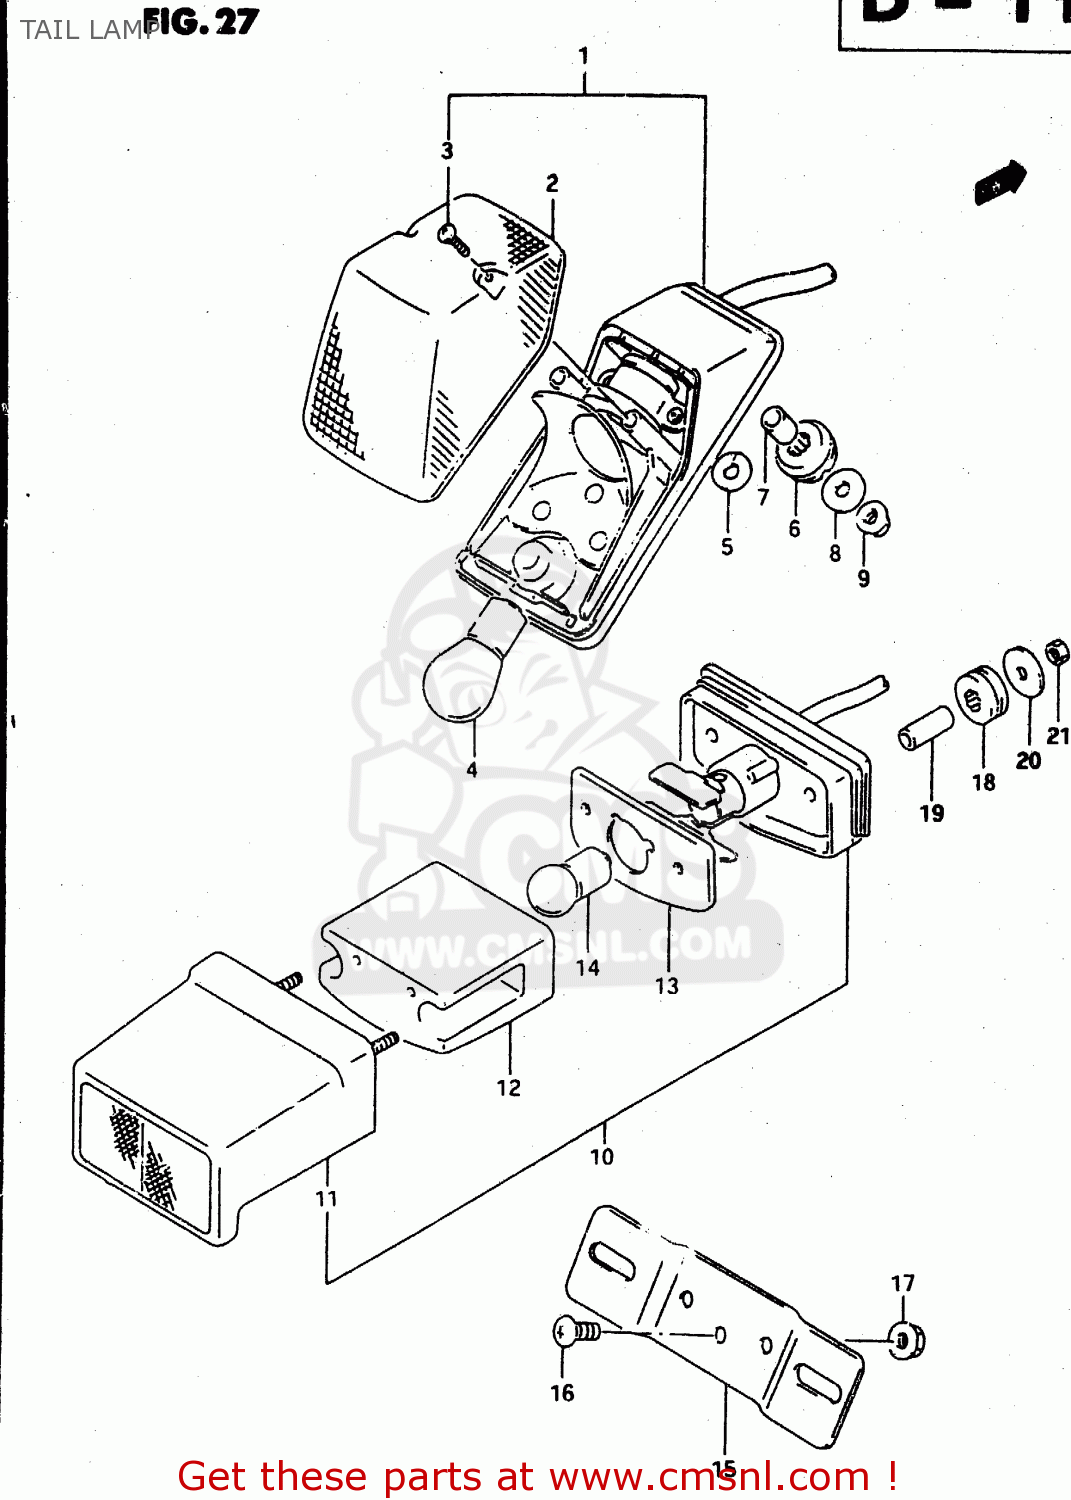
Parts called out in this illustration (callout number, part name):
1	LAMP ASSY,RR COMBINATION
2	LENS
3	SCREW
4	BULB(12V21/5W)
5	GASKET (NAS)
6	CUSHION
7	SPACER(6.4X9.2X12)
8	WASHER(6.5X20X1.6)
9	NUT
10	LAMP ASSY,LICENSE
11	REFLECTOR/COVER
12	LENS
13	GASKET,LICENSE LAMP (NAS)
14	BULB(12V5W,BF150-40160A)
15	PLATE,RR LICENSE
16	SCREW
17	NUT
18	CUSHION
19	SPACER (5.5X9.5X19.50)
20	WASHER(5.5X20X1.2)
21	NUT
